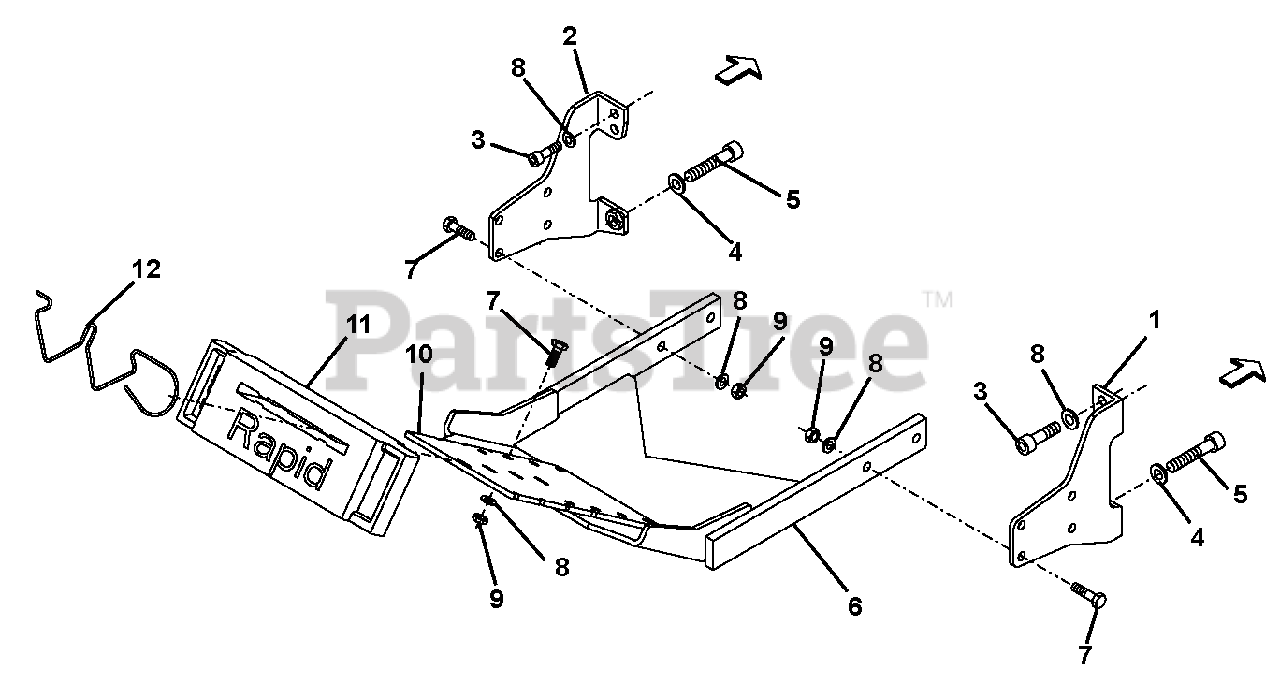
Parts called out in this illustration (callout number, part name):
1	Plate Right
2	Plate Left
3	Screw, D912 M10 x 25
4	Washer, FORM Z 10.2/16.1 x 1.6
5	Screw, Cylinder, D912 M10 x 40
6	Support Weight
7	Hex, Bolt D933 M10 x 30
8	Washer, Form Steel 10.2/20.25 x 1.6
9	Nut, Lock, D934 M10
10	Plate, Adjusting
11	Weight, 8.5 KG
12	Spring, Lock
